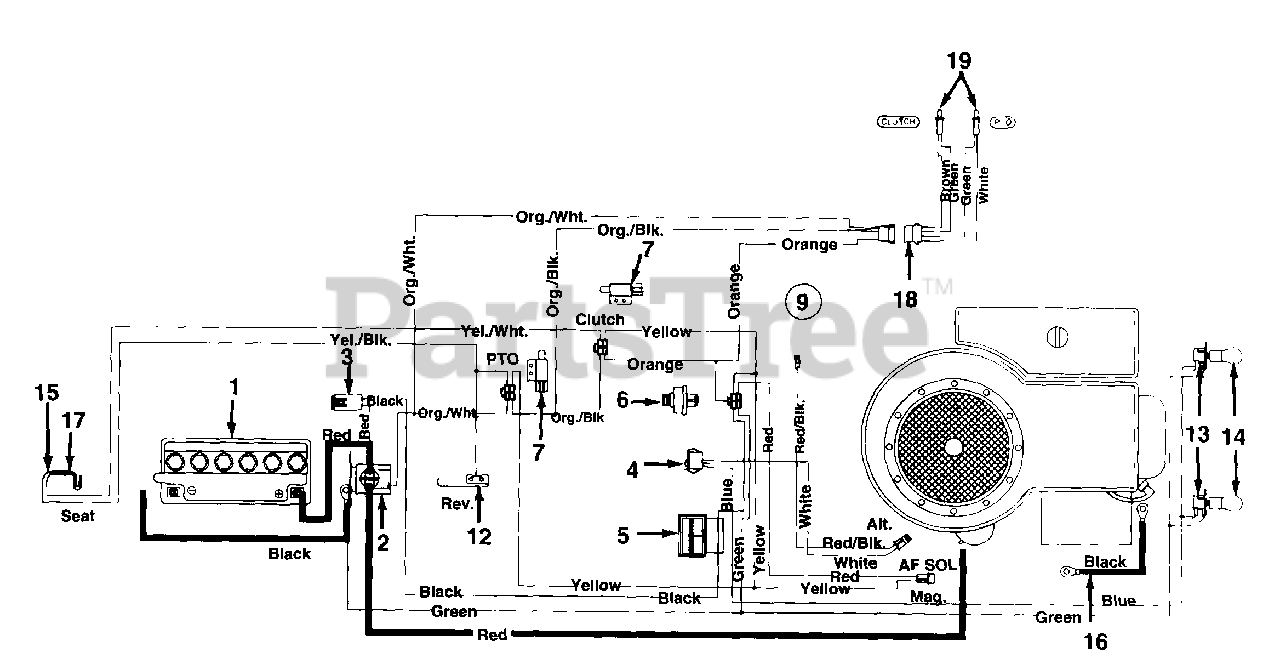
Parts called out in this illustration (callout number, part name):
1	Battery
2	Solenoid
3	Fuse 7.5 Amps
4	Light Switch
5	Ammeter
6	Ignition Switch
7	Safety Switch (Clutch)
9	Wire Harness
12	Safety Switch (Reverse)
13	Socket
14	Bulb (Headlight)
15	Safety Switch (Seat)
16	Ground Wire 7.5" Lg.
17	Safety Switch (Seat)
18	Monitor Harness
19	Monitor Bulb
